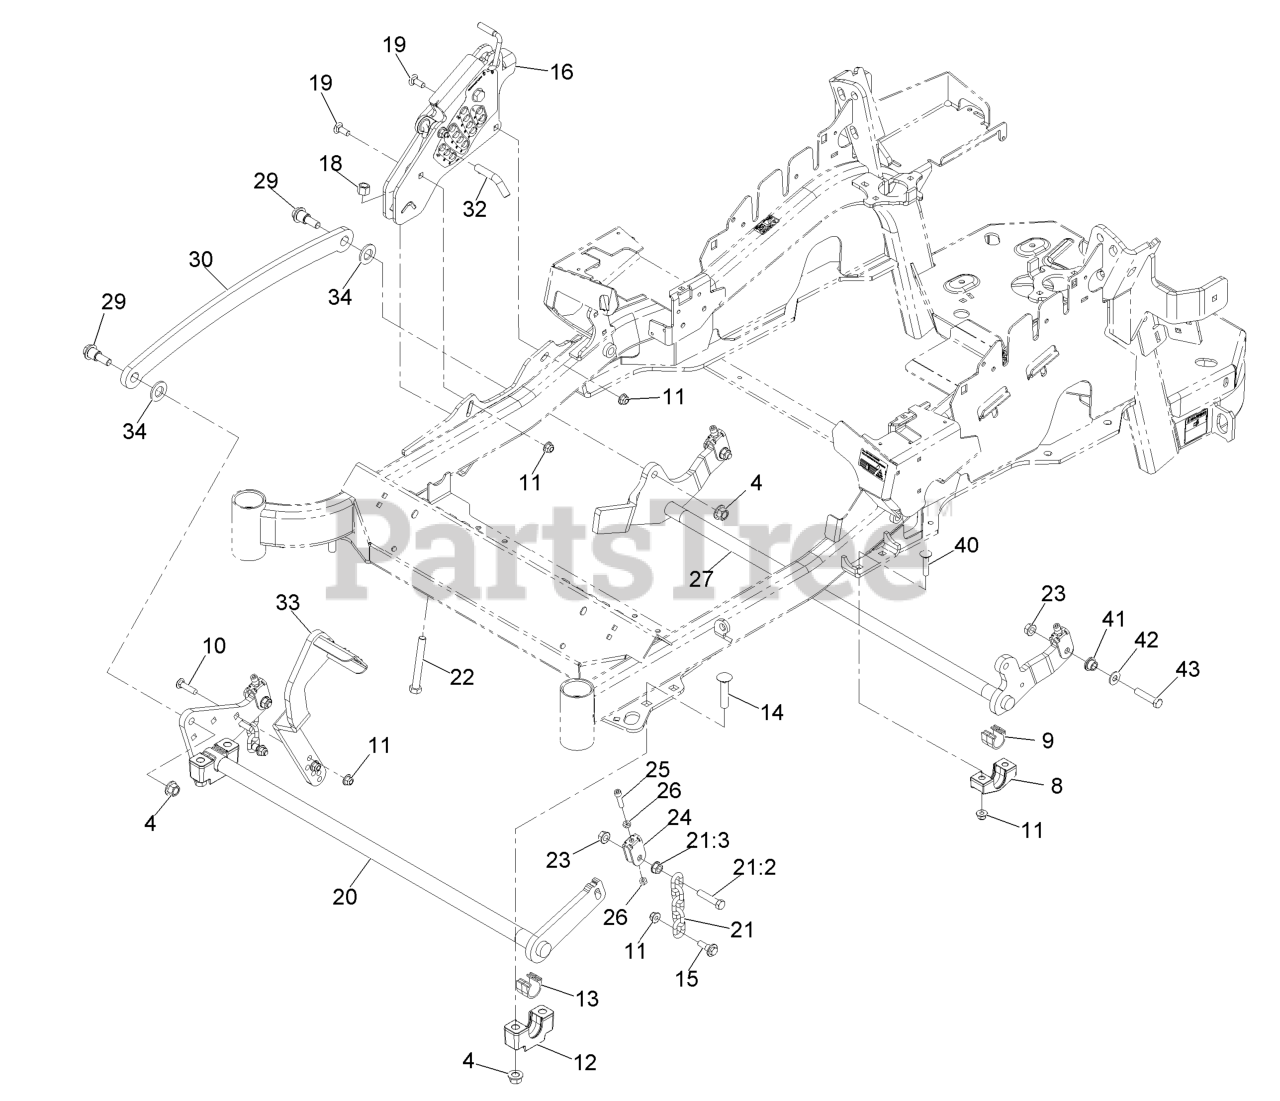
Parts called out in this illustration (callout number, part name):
4	Nut-Lock 1/2-13
9	BEARING-CROSS SHAFT, REAR
10	SCREW-CARR
11	NUT-HF, NI
12	SUPPORT-CROSS SHAFT, BEARING
13	BEARING-CROSS SHAFT, FRON
14	Bolt-Carriage 1/2-13 X 2 1/2 Spl Neck
15	SCREW-SHOULDER, HHF
16	HEIGHT-OF-CUT ASM
18	NUT-LOCK, NI
19	BOLT-CARR
21	DECK LIFT CHAIN ASM
21:2	SCREW-HH
22	BOLT-TAP
24	YOKE-ADJUST, DECK
25	SCREW-HSH
26	NUT-JAM
27	LIFT-DECK, REAR
29	SCREW-SHOULDER, HHF 1/2-13 X 1.12
30	LINK-LIFT, DECK
32	PIN-HOC
33	FOOT LEVER
34	WASHER-FLAT
40	SCREW-CARR
41	BUSHING-FLANGED
42	WASHER-FLAT
43	SCREW-HH
